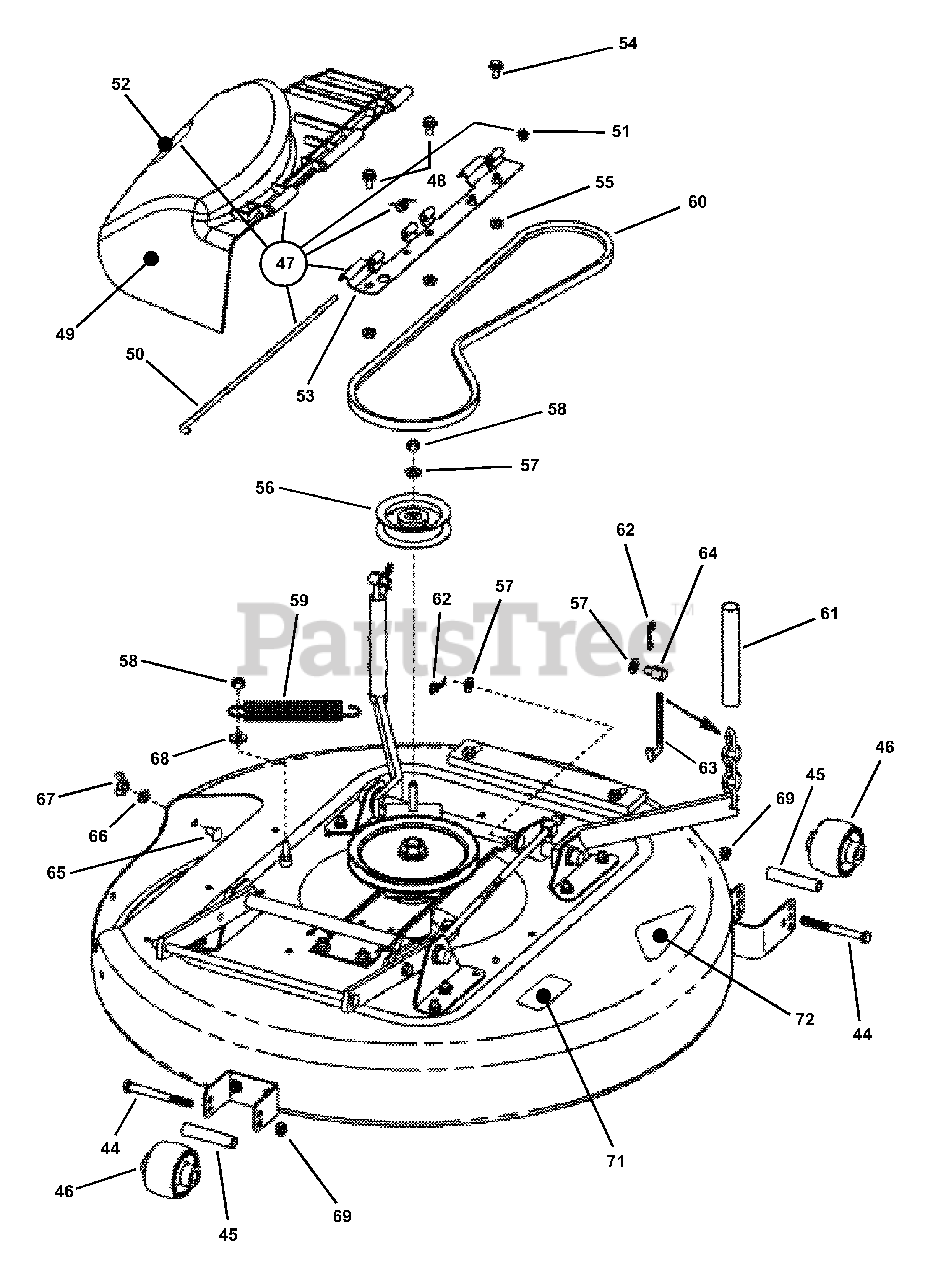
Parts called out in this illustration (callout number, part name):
44	SCREW, 3/8-24 X 3/4" Hex Head Cap, Grade 5
45	SPACER, 3" Long
46	WHEEL, Gage
47	ASSEMBLY, 28" & 33" Discharge Chute
48	SPRING, Hinge
49	CHUTE, Discharge
50	ROD, Chute
51	WASHER, Palnut
52	DECAL, CPSC
53	HINGE, Plastic Side Chute
54	BOLT, 5/16-18 x 5/8" Hex Flange Lock, Grade 5
55	NUT, 5/16-18 Hex Flange Lock, Grade 5
56	IDLER, 4" Outside Diameter Flat
57	WASHER, 3/8" Flat
58	NUT, 3/8-16 Hex Center Lock
59	SPRING, External
60	V-BELT, HA Section, 55.2" Effective Length
61	COVER, Chain
62	HAIRPIN, 3/32 x 1-1/2"
63	ADJUSTER, Chain
64	SWIVEL, Adjustable
65	BOLT, 5/16-18 x 3/4" Short Neck Carriage, Grade 5
66	WASHER, 11/32" Flat
67	NUT, 5/16-18 Wing
68	WASHER, 3/8" Flat
69	NUT, 3/8-24 Hex Center Lock
71	DECAL, Caution
72	DECAL, Hi-Vac
